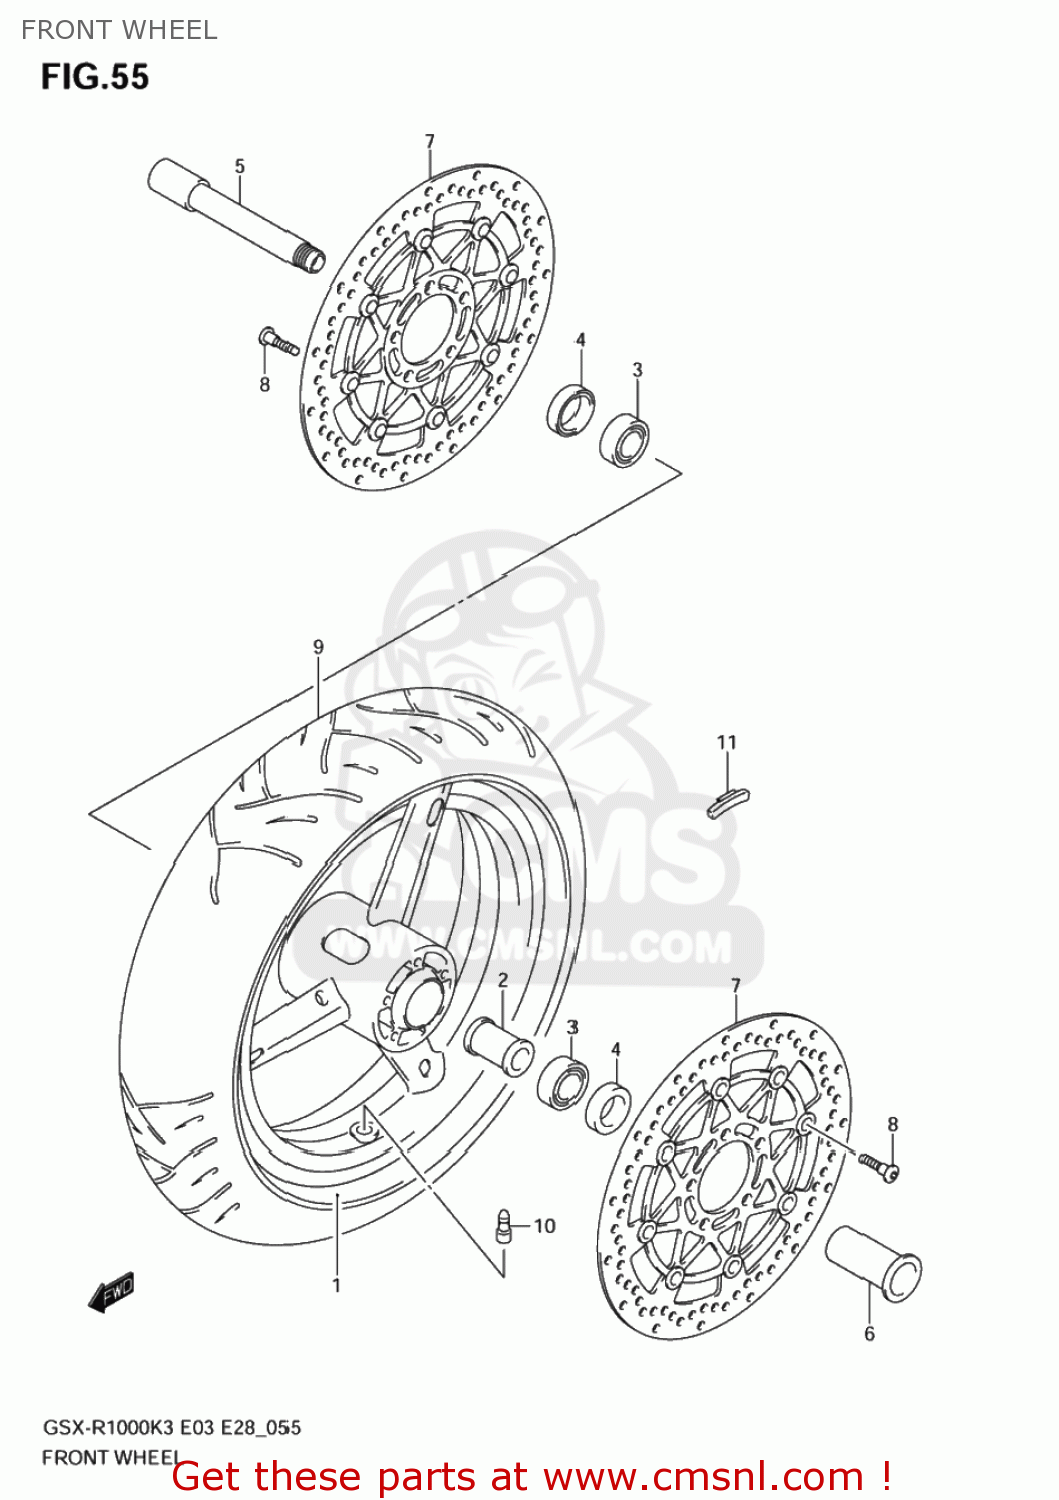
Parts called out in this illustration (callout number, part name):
1	WHEEL FRONT,17
2	SPACER,FRONT HUB BEARING
3	BEARING(25X52X15)
4	SEAL,OIL(32X52X7)
5	AXLE,FR
6	NUT,FR AXLE
7	DISC,FRONT BRA
8	BOLT(8X33)
9	TIRE, FRONT, 120/70ZR17 M/C
10	VALVE ASSY,WHEEL RIM(TR412)
11	WEIGHT,WHEEL BALANCE 10G
